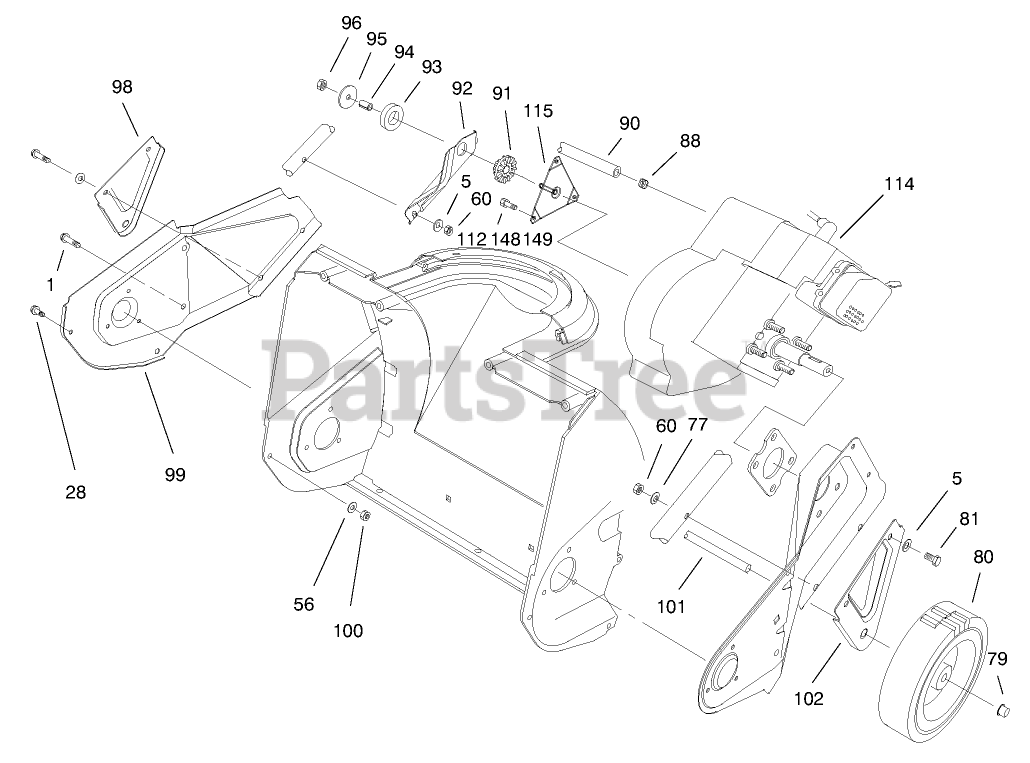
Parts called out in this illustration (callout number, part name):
1	SCREW-PLASTIC
5	WASHER-FLAT
56	WASHER-FLAT
60	NUT-LOCK, NI
77	WASHER
79	RETAINER-PUSH ON
80	WHEEL
81	SCREW-HH
88	CLAMP-HOSE
90	LINE-GAS
91	BUSHING-ISOLATOR
92	Support-Engine
93	Ring-Isolator
94	SPACER-TUBULAR
95	WASHER-FLAT
96	NUT-LOCK, NI
98	Bracket-Wheel
99	Sideplate-RH
100	NUT-LOCK, NI
102	Bracket-Wheel
112	SCREW X
115	BRACKET AND STUD ASM
148	SCREW
149	WASHER-LOCK / EXT
